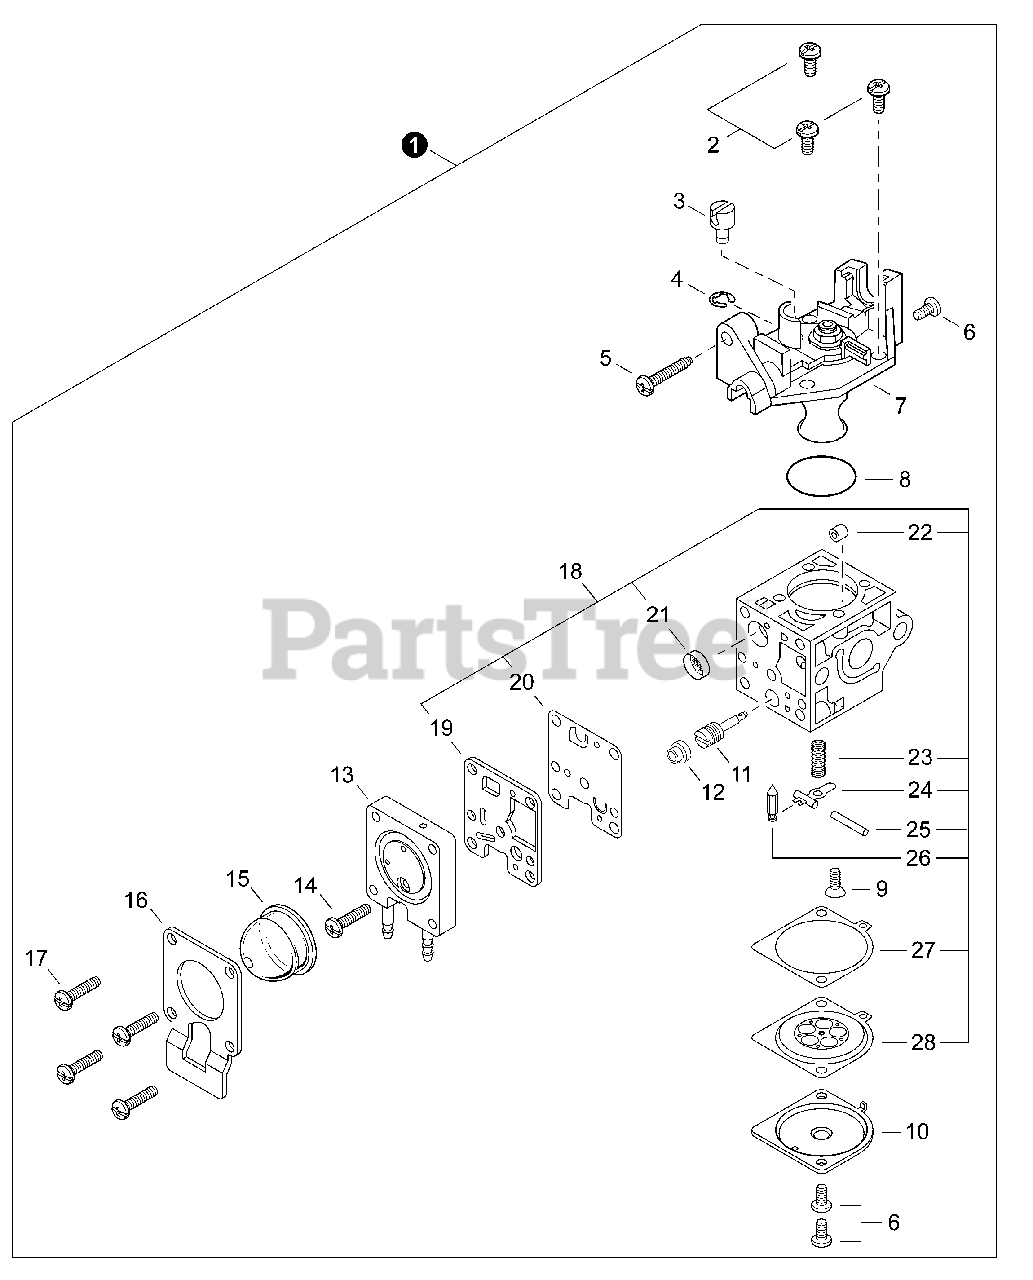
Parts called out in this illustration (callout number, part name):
1	CARBURETOR - RB-K118
5	SCREW, THROTTLE ADJUST
7	COVER ASSY, ROTOR
10	COVER, METERING DIAPHRAGM
11	NEEDLE, HIGH SPEED
12	CAP, LIMITER
13	BODY ASSY, PURGE
15	BULB, PURGE
16	RETAINER, PURGE BULB
18	REPAIR KIT
19	GASKET, PUMP
20	DIAPHRAGM, PUMP
21	SCREEN, FUEL INLET
22	GUIDE, ROLLER
23	SPRING, METERING LEVER
24	LEVER, METERING
25	PIN, METERING LEVER
26	VALVE, INLET NEEDLE
27	GASKET, METERING DIAPHRAGM
28	DIAPHRAGM, METERING
